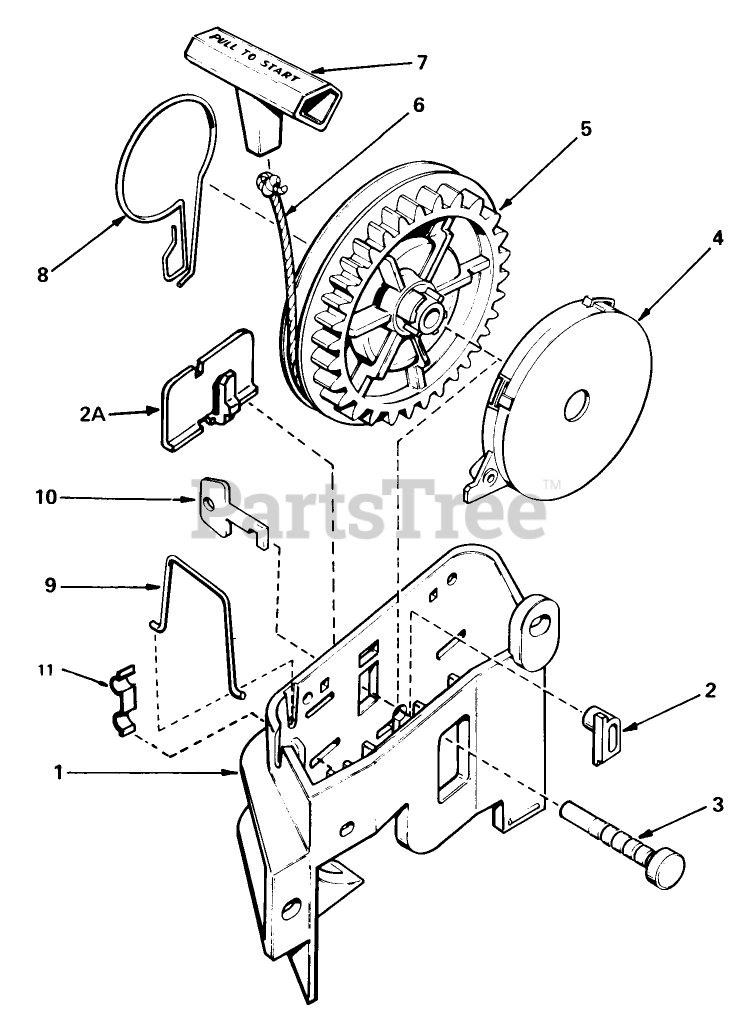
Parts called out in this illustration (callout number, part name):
1	Bracket Starter
2	Pawl, Locking Not used on all engine models)
2A	Clip, Starter Bracket (Used On Starters Not Equipped With Pawl, Ref. No. 2)
3	Pin-Pulley
4	Spring Assy., Rewind (Incl. Ref. #3)
5	Pulley
6	Rope Starter (Length 65" 9/64" Dia.)
7	Handle-Starter
8	Brake
9	Clip-Rope
10	Key (Not Used On All Engine Models
11	Washer-Thrust
